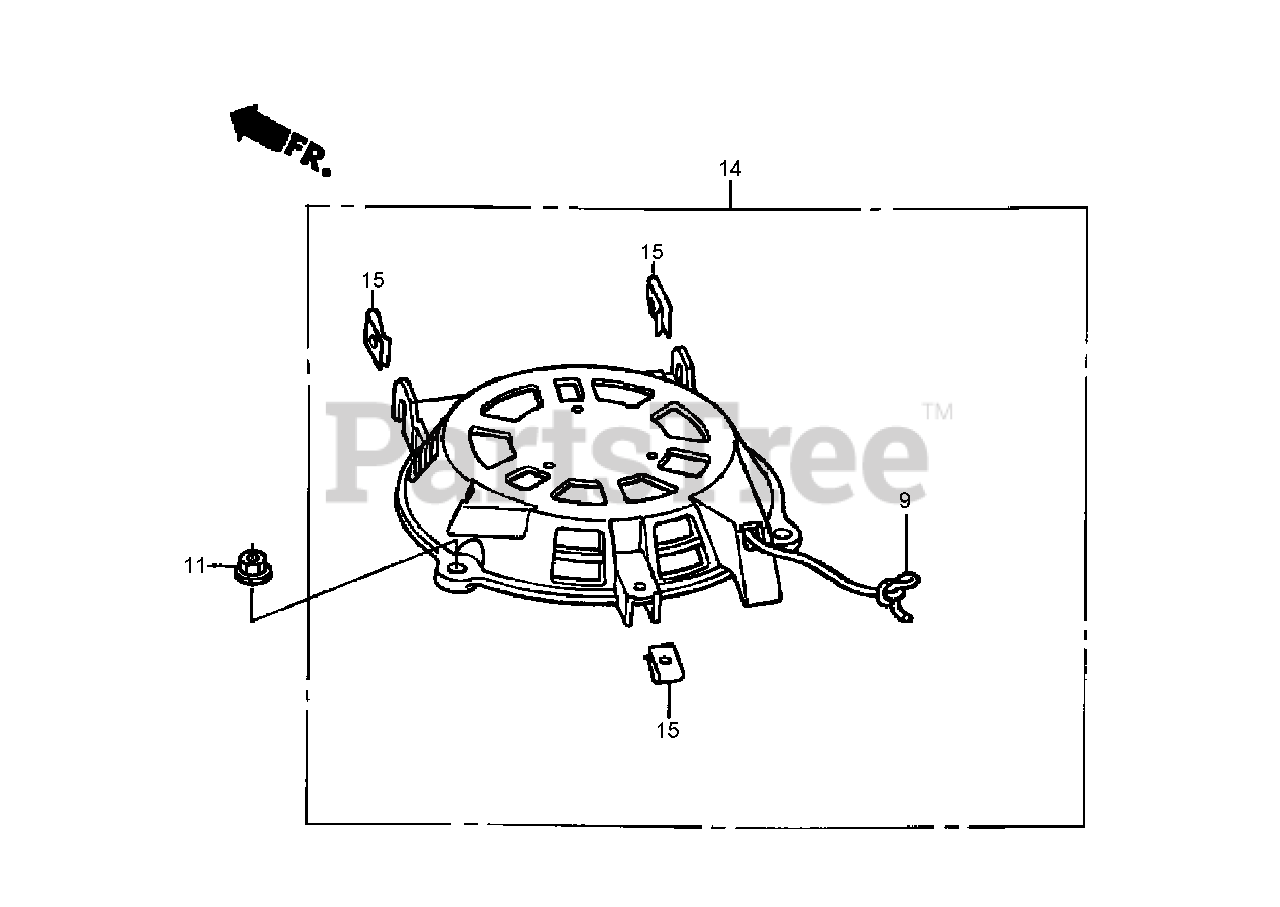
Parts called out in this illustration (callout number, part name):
9	ROPE-STARTER, RECOIL
11	NUT-FLANGE (6MM)
14	RECOIL STARTER ASM
15	NUT-COWL
